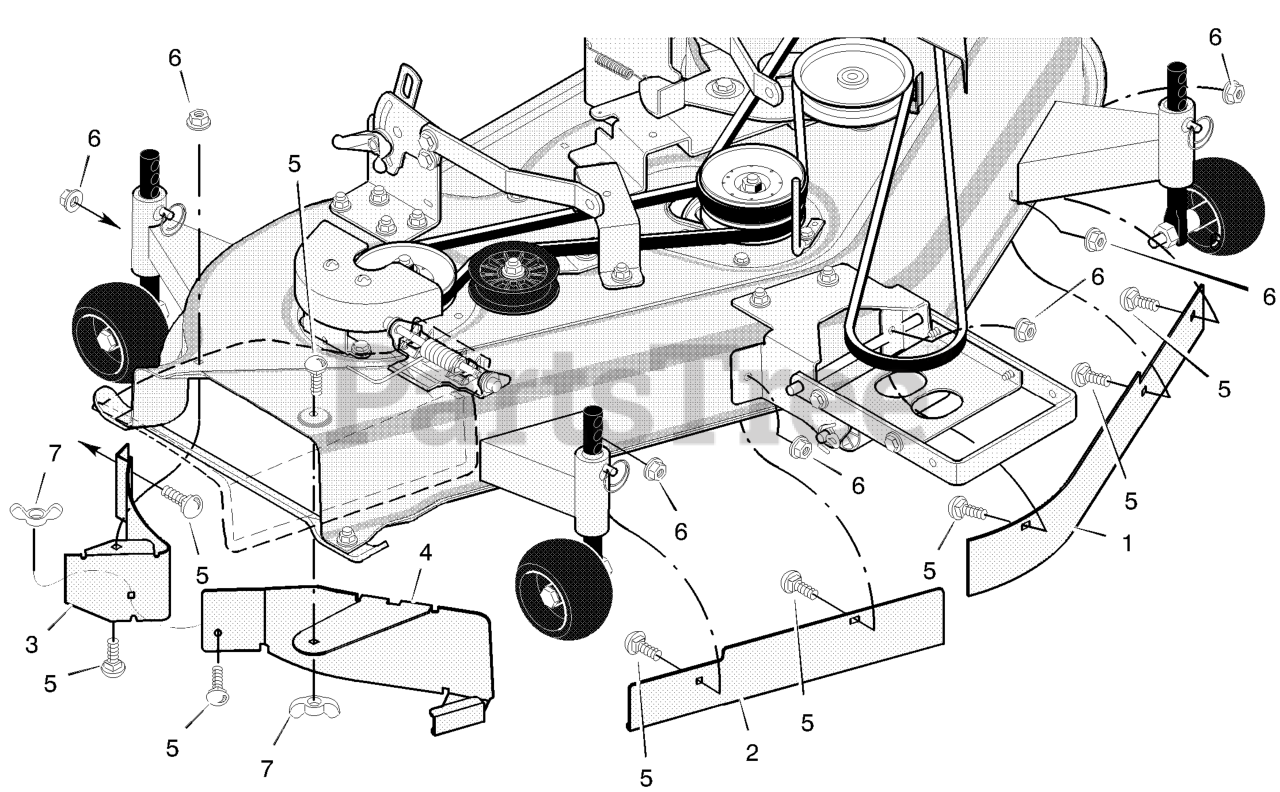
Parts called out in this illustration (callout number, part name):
1	Baffle, Left
2	Baffle, Right
3	Baffle, Inner
4	Plate, Mulcher
5	Bolt, Carriage
6	Nut, Flange
7	Wingnut
